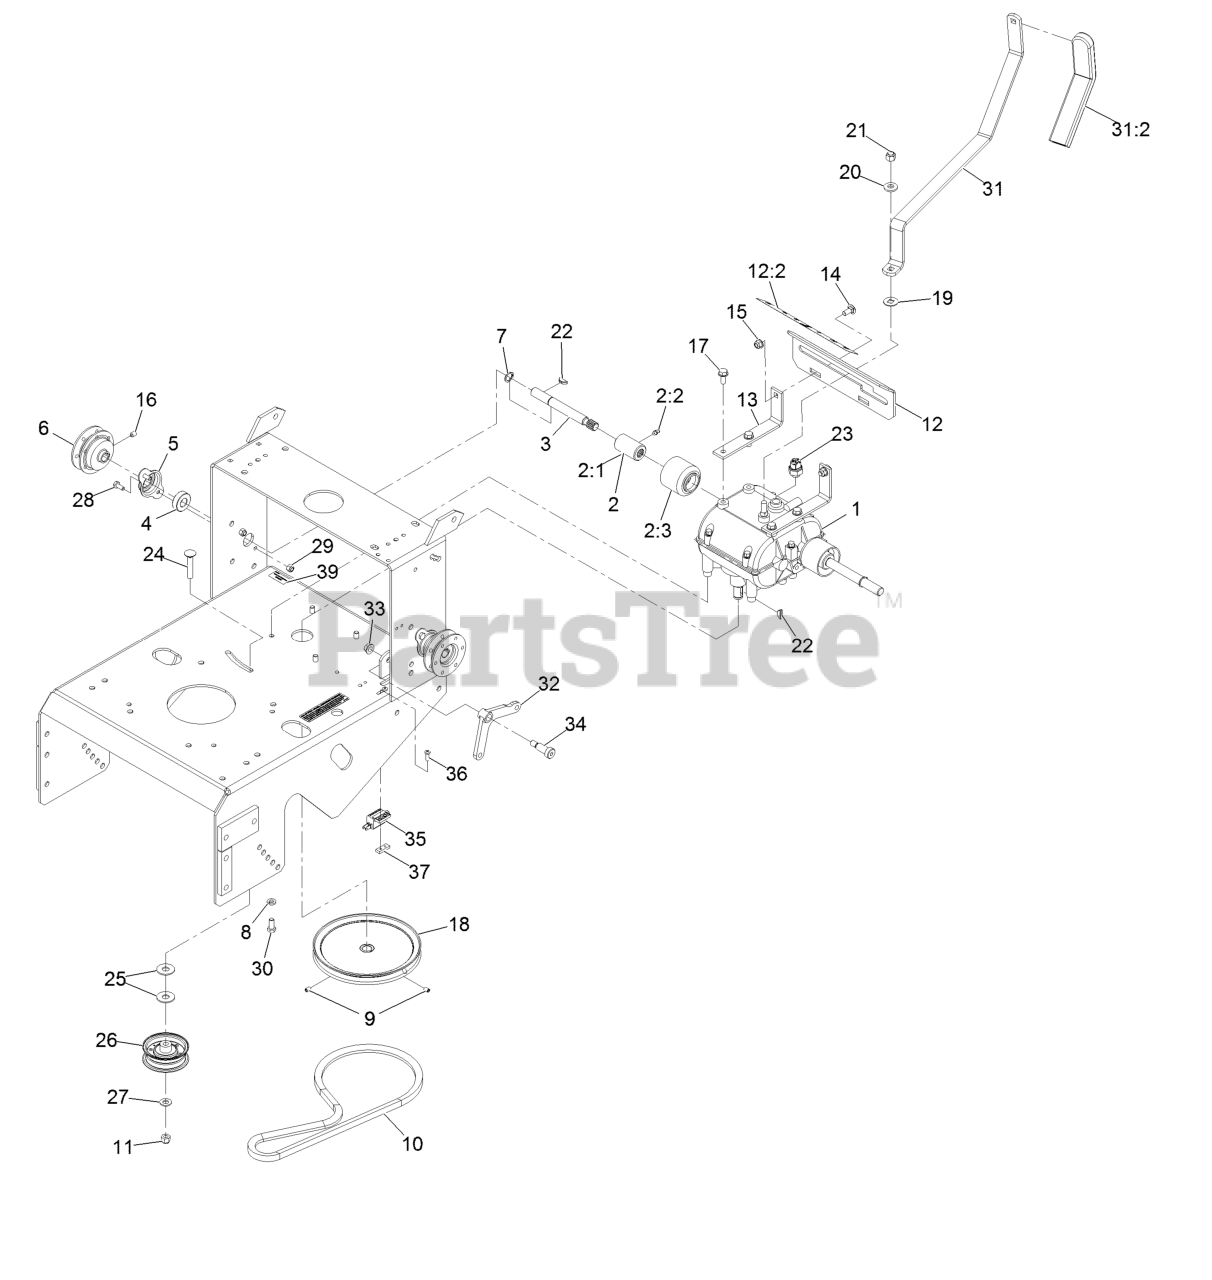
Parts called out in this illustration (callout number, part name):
1	Transmission-5 Speed
2	Coupling, W/Guard And Zerk
2:1	Coupler
2:2	Zerk-1/4-28 Str
2:3	Guard-Coupler
3	Shaft-Transmission
4	Bearing-Shaft
5	Flange-Output
6	Sheave-Transmission
7	Ring-Retaining
8	Washer-Lock 5/16 Heavy
9	Setscrew-1/4-20 X 3/8
10	Belt, Transmission Drive
11	Nut-Nyloc 3/8-16
12	Asm, Shifter Plate W/ Decals
12:2	Decal-Speed, Ground
13	Bracket-Plate, Shift
14	Bolt-Carriage 5/16-18 X 3/4
15	Nut-Nyloc 5/16-18 Flg
16	Setscrew-5/16-18 X 3/8
17	Screw-HWH 5/16-18 X 3/4 Tf
18	Sheave-Transmission
20	Washer-Spring Disc 3/8
21	Nut-Nyloc 3/8-24
22	Key-Woodruff #9 3/4 X 3/16
23	Switch-Start, Neutral
24	Bolt-Carriage 3/8-16 X 2
25	Washer-7/16 Std
26	Pulley-Idler, Flat
27	Washer-3/8 SAE
28	Screw-HH 1/4-20 X 5/8
29	Nut-Nyloc 1/4-20
30	Screw-HH 5/16-18 X 3/4
31	Lever, Shift W/Grip
31:2	Grip Foam
32	Bellcrank
33	Nut-Whizlock 3/8-16
34	Bolt-Shoulder
35	Switch-N.O.
36	Screw-PPH #10-24 X 5/8
37	Plate-Tapped
39	Decal-Patent
